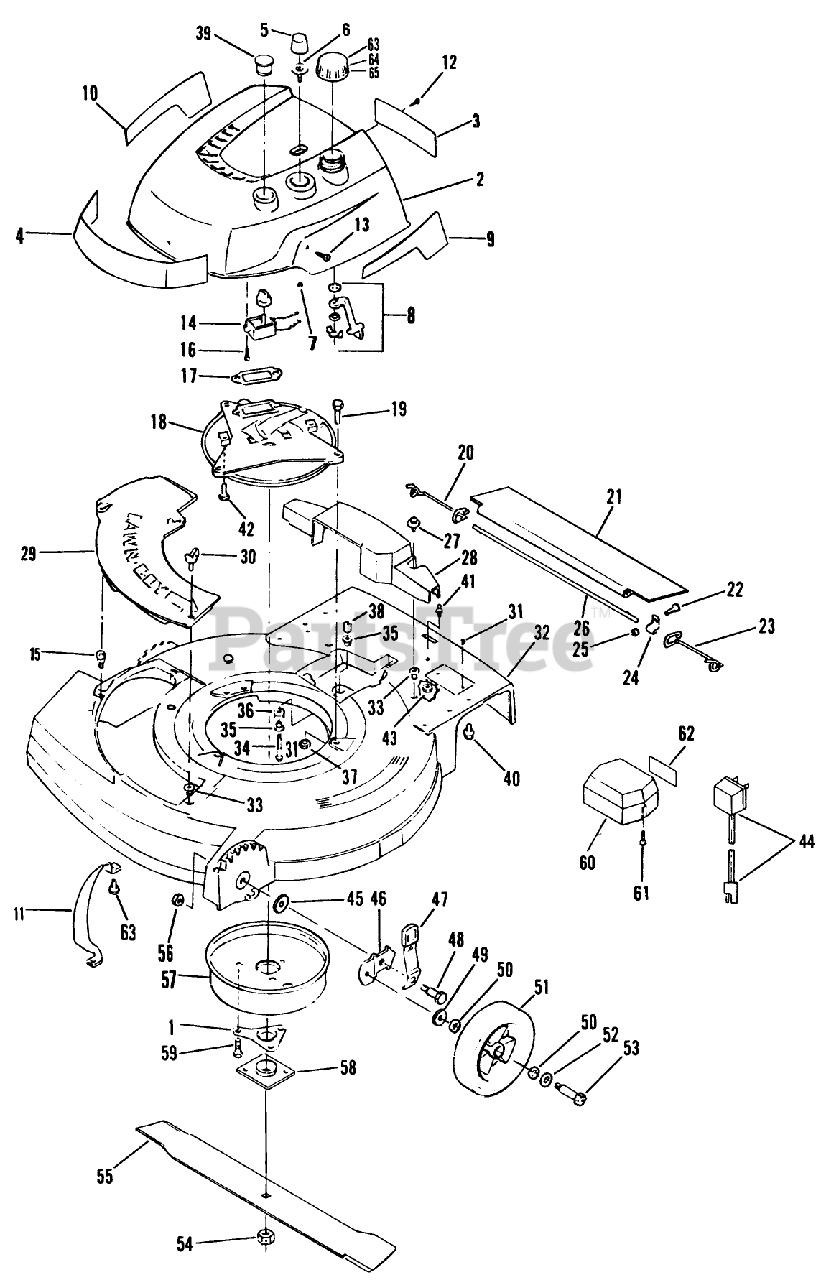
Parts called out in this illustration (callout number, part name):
1	SUPPORT F
7	LOCKNUT S
11	BAR-TOE
12	SCREW S
13	SCREW S
14	SWITCH
19	SCREW
20	SPRING;TRAILING SHIELD RH
21	SHIELD
23	SPRIG T/SHLD ASOC
24	CLAMP ROD KMC
25	LOCKNUT E
26	ROD 21" ADVANCE
27	SCREW SEMS TRM HEX HD
30	WING SCREW LAWRE
35	SPACER ECK PRES
36	GROMMET
37	NUT-LOCK F
38	SPACER
39	F-PLUG
40	SCREW
42	SCREW V
45	WASHER
49	WASHER WROUGHT
50	WASHER
52	SPACER
53	BOLT WHEEL
54	NUT-BLADE
56	LOCKNUT
57	MUFFLER COVER F
58	PLATE AND COLLAR ASM
59	SCREW
64	BAFFLE - FOAM SM
65	GASKET S
